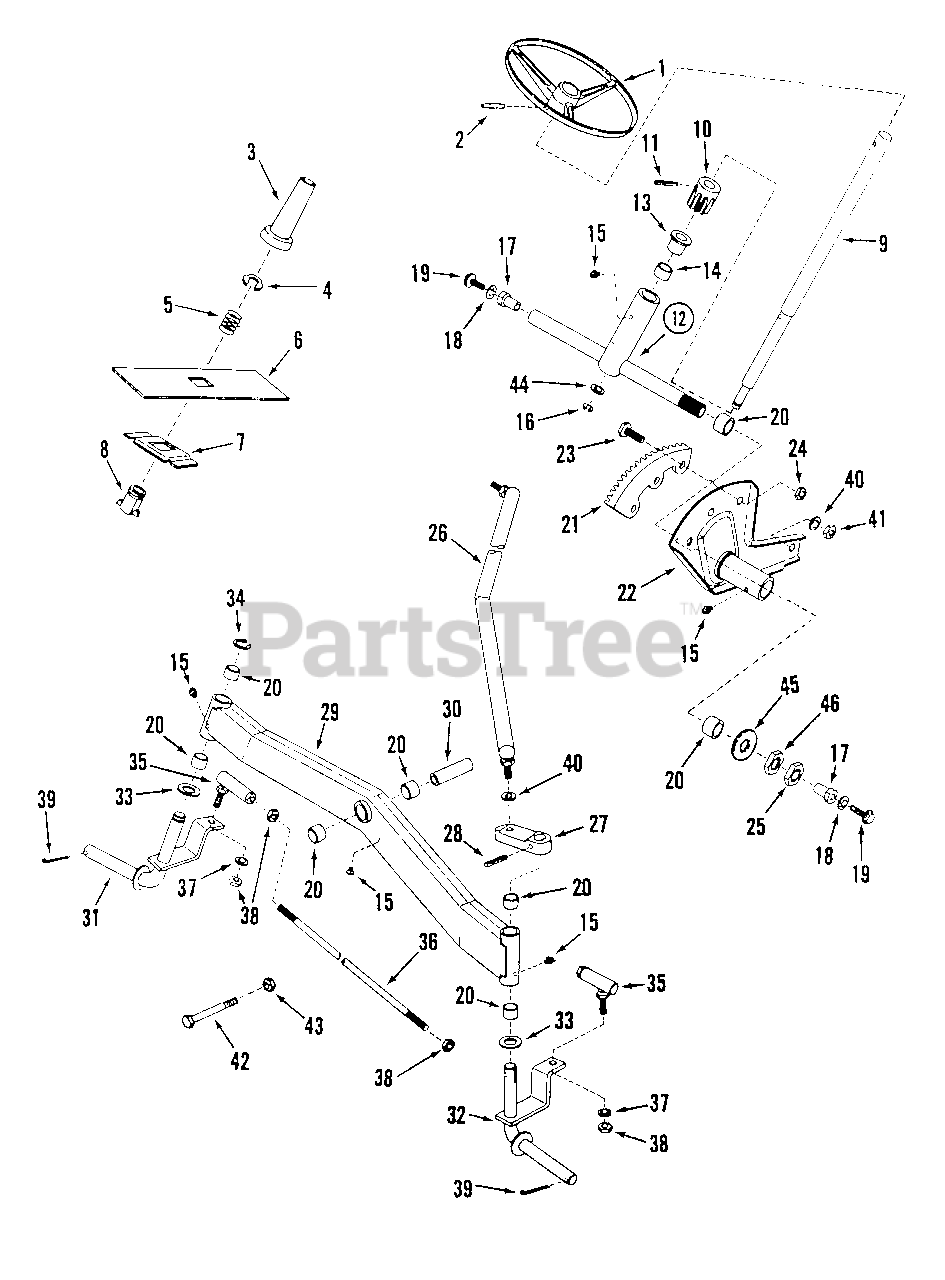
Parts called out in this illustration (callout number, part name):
1	STEERING WHEEL
2	ROLL-PIN, 1/4" x 2-1/4"
3	ACTUATOR, Steering Lock (NLA)
4	RING, 13/16" External Retaining
5	SPRING, Actuator
6	COVER, Slide
7	RISER, Steering Lock
8	BUSHING, Steering Lock
9	SHAFT, Steering (Current Models)
10	PINION, Steering
11	ROLL-PIN, 3/16 x 1-1/2"
12	ASSEMBLY, Bearing Support
13	BEARING, Flange .875 OD x .630 ID x .75 Long
14	BEARING, 7/8X5/8, PM
15	LUBE FITTING, Straight (press-fit for .187 dia. Hole)
16	SNAP-RING, 5/16
17	PIVOT
18	WASHER, 5/16 Internal Tooth Lock
19	SCREW, 5/16-18 x 3/4" Hex Washer Self-Tap
20	BEARING, Sleeve, .875 OD, PM
21	QUADRANT, Steering
22	ASSEMBLY, Sector
23	SCREW, 1/4-20 x 5/8" Hex Head Cap, Grade 5
24	NUT, 1/4-20 Hex Center Lock, Grade B or 5
25	NUT, 3/4-16 Hex Jam
26	DRAG-LINK
27	ARM, Steering
28	ROLL-PIN, 1/4 x 1-1/4"
29	ASSEMBLY, Front Axle
30	JOURNAL, Axle .75x.51x3.03
31	KING-PIN, Right Side
32	KING-PIN, Left Side
33	WASHER, Thrust 1.62x.775x.025
34	RING, 3/4" External Retaining
35	BALL JOINT, 3/8-24 Thread
36	TIE-ROD
37	WASHER, 3/8" Split Lock
38	NUT, 3/8-24 Hex, Grade 2
39	COTTER-PIN, 5/32 x 1"
40	WASHER, 1/2 Split Lock
41	NUT, 1/2-20 Hex, Grade 2
42	SCREW, 1/2-20 x 4" Hex Head Cap, Grade 5
43	NUT, 1/2-20 Hex Thin Lock
44	WASHER, 3/8" Flat
45	WASHER, 3/4" I.D. Flat
46	NUT, 3/4-16 Hex
